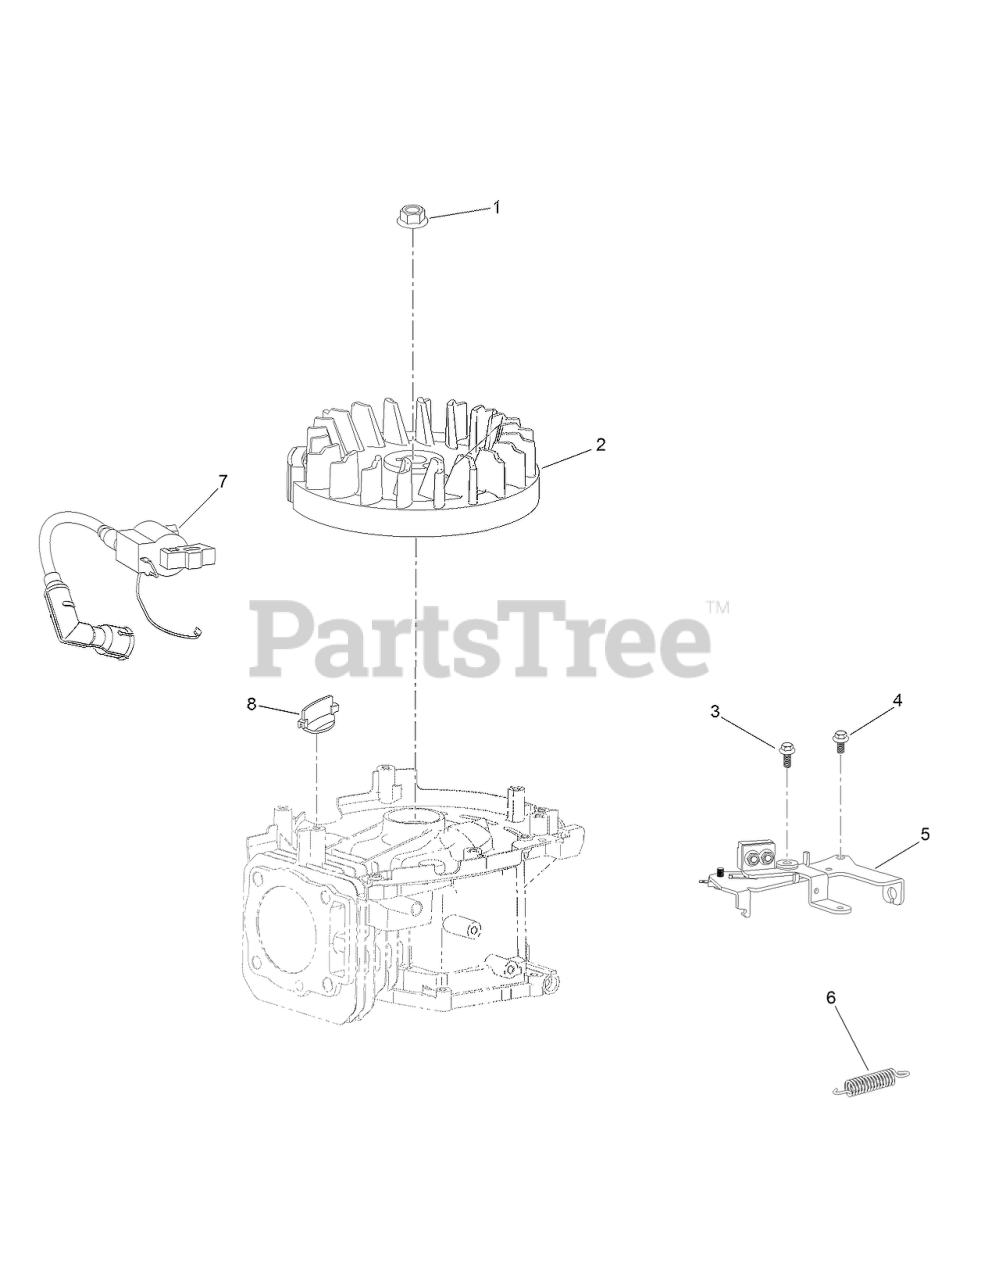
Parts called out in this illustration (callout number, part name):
1	NUT-FLANGE
2	FLYWHEEL
3	BOLT-FLANGE
4	SCREW-HHF
5	BRAKE ASM
6	SPRING-BRAKE
7	IGNITION COIL ASM
8	GUARD-FLYWHEEL
